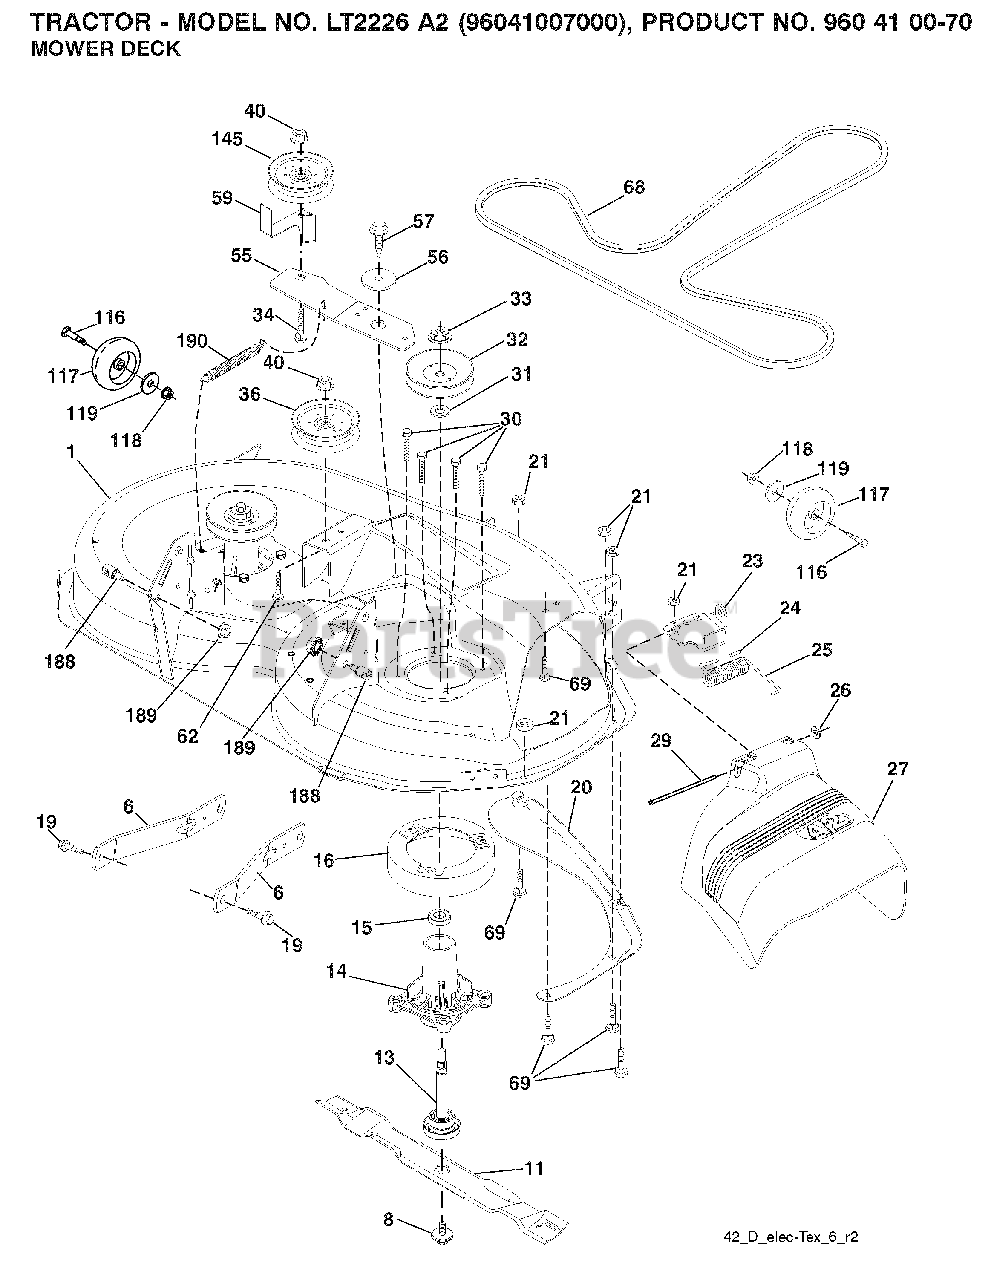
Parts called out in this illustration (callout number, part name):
1	DECK.WELDMENT.42"
6	ARM.SUSPENSION.MOWER.R
8	BOLT.WASHER.ASM.7/16-2
11	42" HI-LIFT BLADE
13	SHAFT.ASM.MDRL.N/GREASE.38
14	HOUSING MANDREL
16	STRIPPER, MWR ROUND
19	BOLT.SHOULDER
20	BAFFLE.VORTEX
21	LOCKNUT
23	BRKT.DEFLECTOR.38"2005+
24	CAP-SLEEVE LT
25	SPRING.TORSION.DEFLECT
26	NUT PUSH M
27	SHIELD.DEFLECTOR.MOWER.42"BLAC
29	ROD.HINGE
30	SCREW, WASHER HEAD
31	WASHER.SPACER.MANDREL
32	PULLEY/MANDREL
33	NUT.FLANGE.LOCK.TOP
34	BOLT.3/8-16X1.50
36	PULLEY.IDLER.2006
40	NUT LOCK FLG 3/8-16 UNC
55	IDLER.ARM
56	SPACER.RETAINER
57	SCREW 3/8-16X1
59	GUARD, BELT
62	BOLT
68	BELT V SECONDARY
69	BOLT
117	WHEEL.GAGE.HALF.SPOKED
118	LOCKNUT
119	WASHER
145	PULLEY.IDLER.48"PRIMARY
188	STUD.FASTNER.W/ANTI-ROTATE
189	NUT LOCK HEX FLANGE 5/16-18
190	SPRING.MOWER.DRIVE.ELECTRIC
